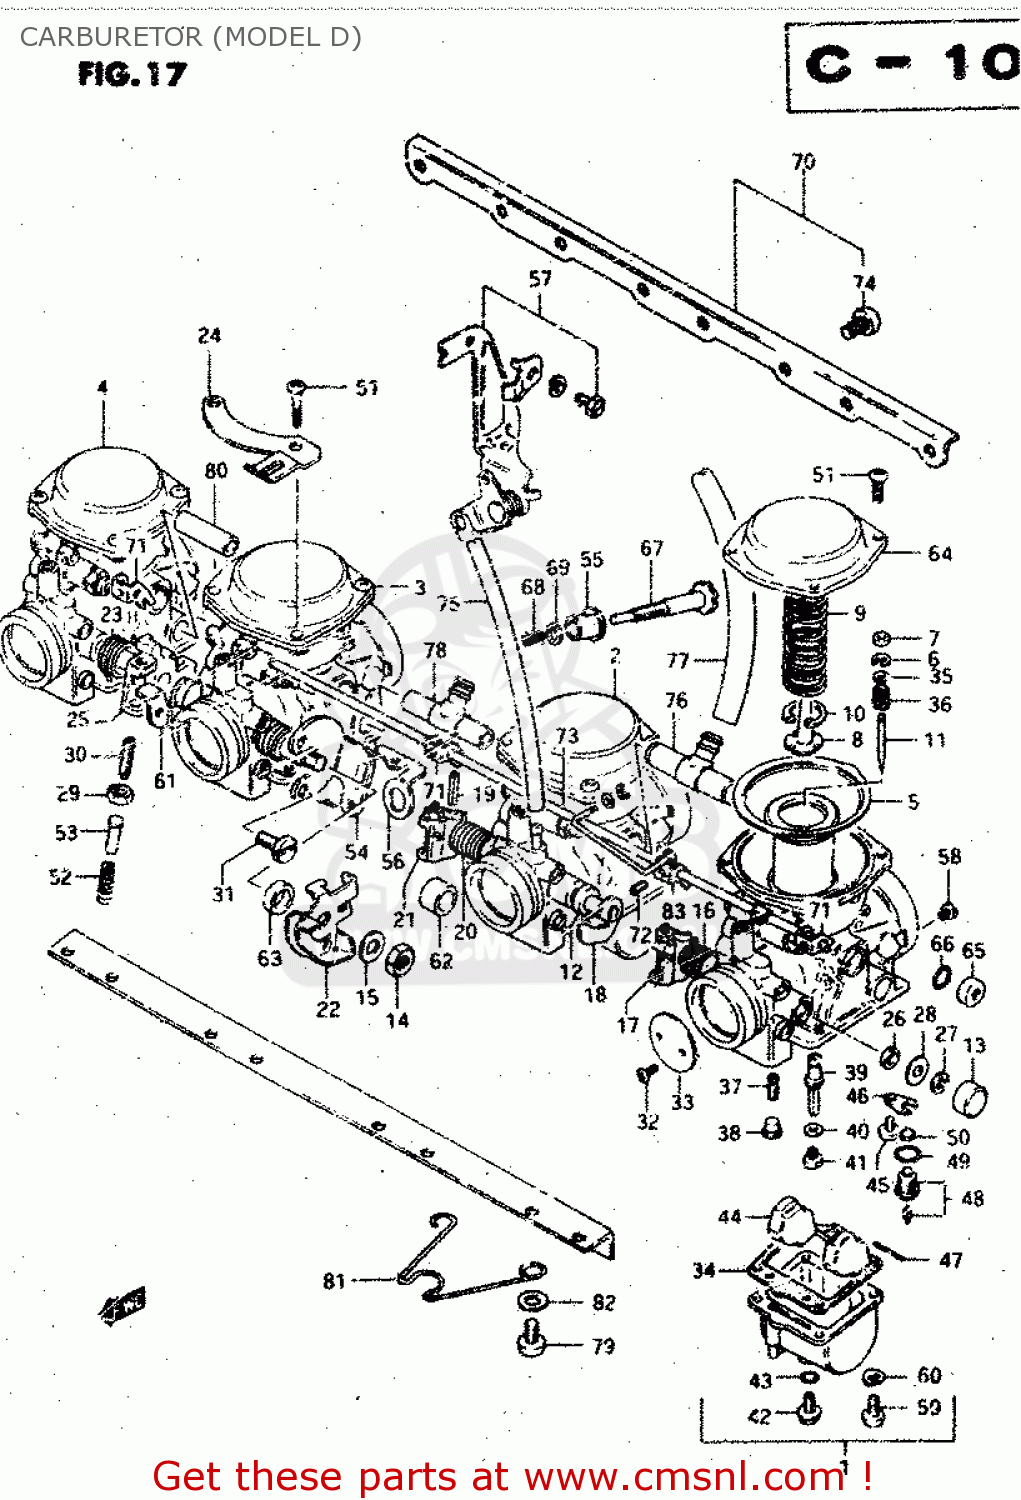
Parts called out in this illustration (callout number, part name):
1	CARBURETOR, LH
2	CARBURETOR, ML
3	CARBURETOR, MR
4	CARBURETOR, RH
5	DIAPHRAGM
6	CLIP,NEEDLE
7	RING
8	HOLDER,GUIDE
9	SPRING
10	E RING
11	NEEDLE, JET (5057-2)
12	GASKET
13	CAP,THROTTLE SHAFT
14	NUT 8MM
15	WASHER
16	SPRING,THROTTLE SHAFT
17	SHAFT,THROTTLE
18	SHAFT ASSEMBLY
19	PIN,THROTTLE SHAFT
20	SPRING,THROTTLE SHAFT
21	LEVER,THROTTLE SHAFT
22	LEVER ASSEMBLY,THROTTLE
23	SPRING,THROTTLE SHAFT
24	BRACKET
25	SHAFT,THROTTLE
26	SEAL
27	E RING
28	GASKET,THROTTLE SHAFT (NAS)
29	NUT
30	SCREW
31	SCREW
32	SCREW
33	VALVE,THROTTLE (BUTTERFLY)
34	GASKET,FLOAT CHAMBER (NAS)
35	WASHER
36	SPRING
37	JET,PILOT(42.5)
38	PLUG,NEEDLE JET
39	JET, NEEDLE (X-2)
40	WASHER,NEEDLE NOZZLE
41	JET,MAIN(112.5)
42	PLUG,DRAIN
43	GASKET (NAS)
44	FLOAT
45	SCREW 4X6
46	PLATE,NEEDLE VALVE FITING
47	PIN,FLOAT
48	VALVE ASSEMBLY,NEEDLE
49	O-RING,NEEDLE VALVE
50	FILTER
51	SCREW
52	SPRING
53	PIN,THROTTLE LEVER
54	BRACKET,THROTTLE ADJUST
55	BUSH
56	BRACKET,THROTTLE ADJUST
57	BRACKET,THROTTLE
58	JET,AIR
59	SCREW
60	WASHER,LOCK
61	SHAFT,THROTTLE
62	RING
63	RING
64	COVER,DIAPHRAGM
65	CAP,STARTER VALVE
66	O RING
67	SCREW
68	SPRING
69	WASHER
70	CARBURETOR ASSEMBLY
71	LEVER
72	SCREW
73	SHAFT,STARTER
74	SCREW
75	HOSE
76	NIPPLE
77	HOSE
78	NIPPLE
79	SCREW
80	NIPPLE
81	CLIP
82	WASHER
83	LEVER ASSY
